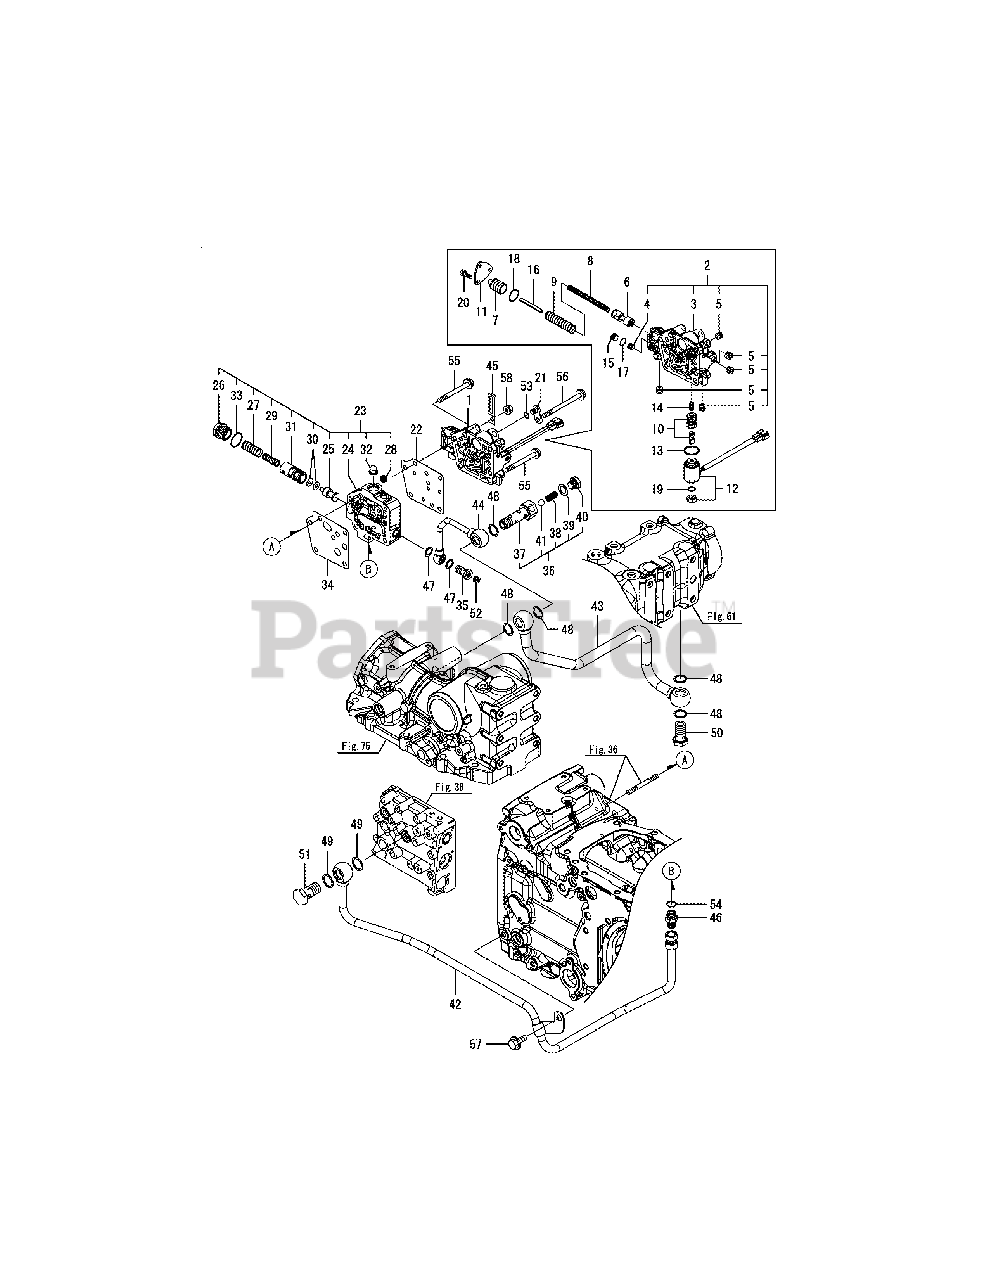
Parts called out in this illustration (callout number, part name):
2	VALVEBODY(A CMP
5	PLUG PT1/8,SCREW
6	MODULATION VALVE
7	PISTON(ACCUMULATOR
10	VALVE ASSY, SOLENOID
13	GASKET, SOLENOID
14	SPRING,SOLENOID
16	PIN 6.0AX60,SPRING
17	O-RING 1A P-7.0
18	O-RING 1A P-24.0
19	O-RING 1A S-11.2
22	GASKET, PTO VALVE
24	CASE, PLATE PTO
27	SPRING, RELEASE
29	SPRING, RELEASE
33	O-RING, 1A 24023
34	PK, VALVE PLATE
35	BOLT M14,PIPE JOINT
36	HOLDER,RELIEF ASSY
39	GASKET 16, ROUND
43	LP PIPE, REAR HOUSING
45	CLAMP, WIRE HARNESS
47	GASKET 14, ROUND
50	BOLT, JOINT M15
52	PLUG PT1/8,SCREW
53	O-RING 1A P-7.0
54	O-RING 1A P-14.0
55	BOLT M 8X 80 PLATED
56	BOLT M 8X100 PLATED
57	BOLT M10X 20 PLATED
